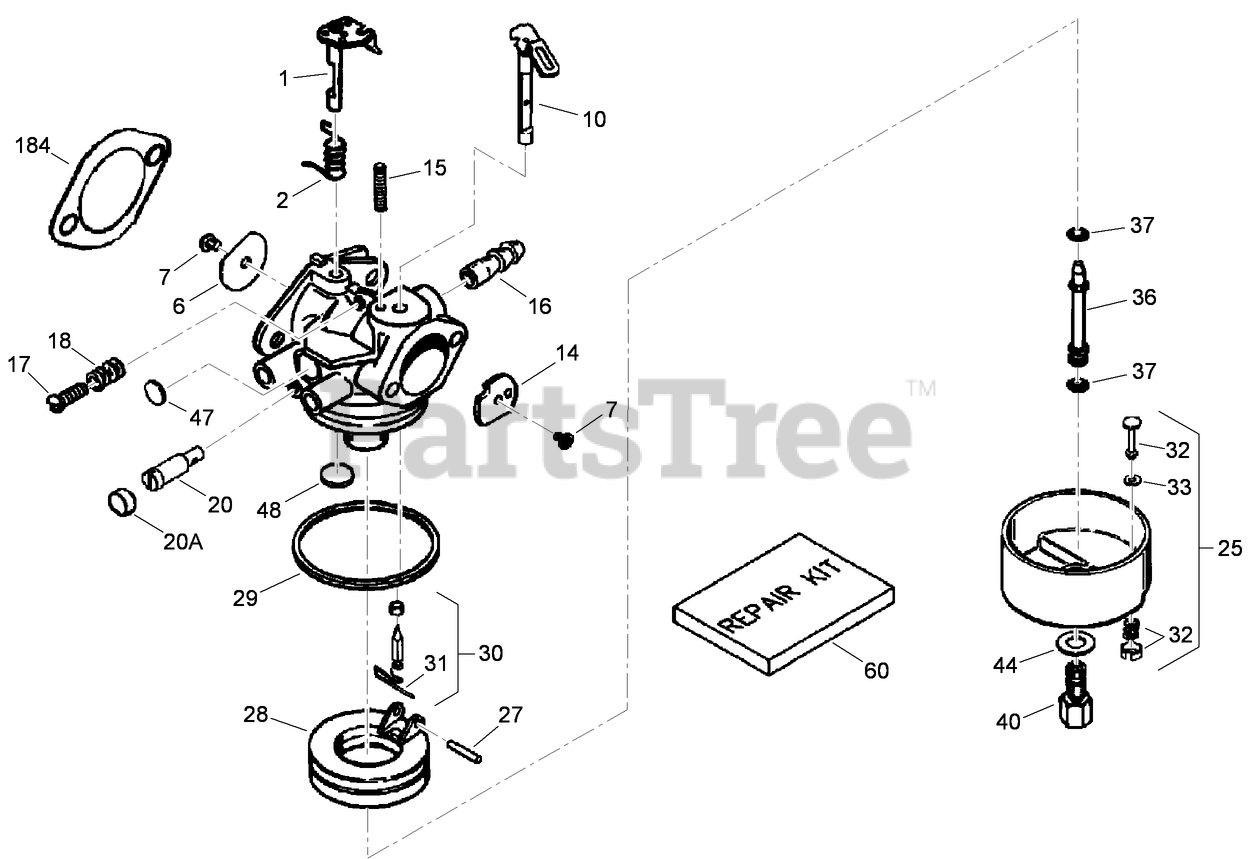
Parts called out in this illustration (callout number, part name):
1	Throttle Shaft and Lever ASM
2	Spring-Return, Throttle
6	Shutter-Throttle
7	Screw-Shutter
10	Choke Shaft and Lever ASM
14	Shutter-Choke
15	Spring-Positioning, Choke
16	Fitting-Fuel
17	Screw-Throttle Crack and Idle Speed
18	Spring-Tension
20	Screw-Restrictor, Idle
20A	Cap-Screw, Restrictor Idle
25	Float Bowl Asm. (Incl. Ref. # 32, 33)
27	Shaft-Float
28	Float (Plastic)
29	O Ring-Bowl, Float
30	Inlet Needle, Seat and Clip ASM (Includes 31)
31	Clip-Spring
32	Bowl Drain ASM
33	Gasket-Plunger, Drain
36	Tube-Nozzle
37	O-Ring
40	Nut-Bowl, High Speed
44	Washer-Bowl Nut
47	Plug-Welch, Idle Mixture Well
48	Plug-Welch, Atmospheric Vent
60	Carburetor Repair Kit
184	Gasket-Carburetor To Intake Pipe
